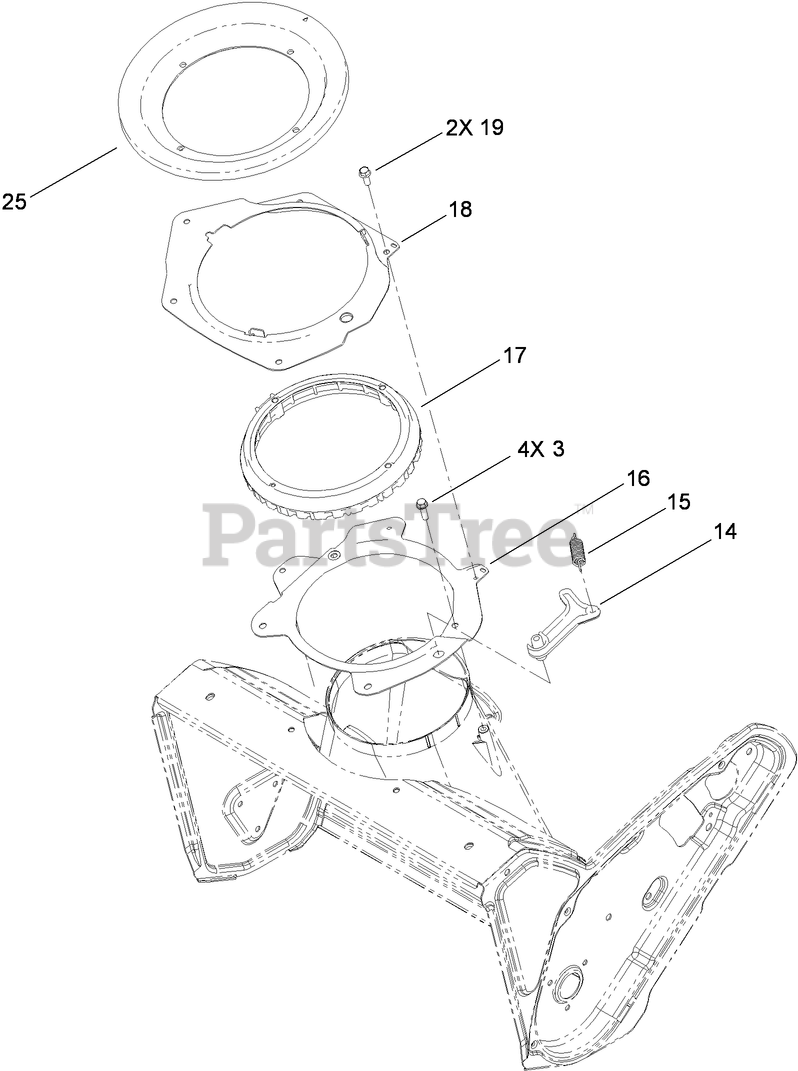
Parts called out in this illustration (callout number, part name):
3	SCREW-HWH
14	PAWL-DETENT
15	SPRING-EXTENSION
16	RING-SUPPORT, CHUTE
17	RING-CHUTE, DETENT
18	RETAINER-RING, CHUTE
19	SCREW-HWH
25	SEAL-RING, CHUTE
